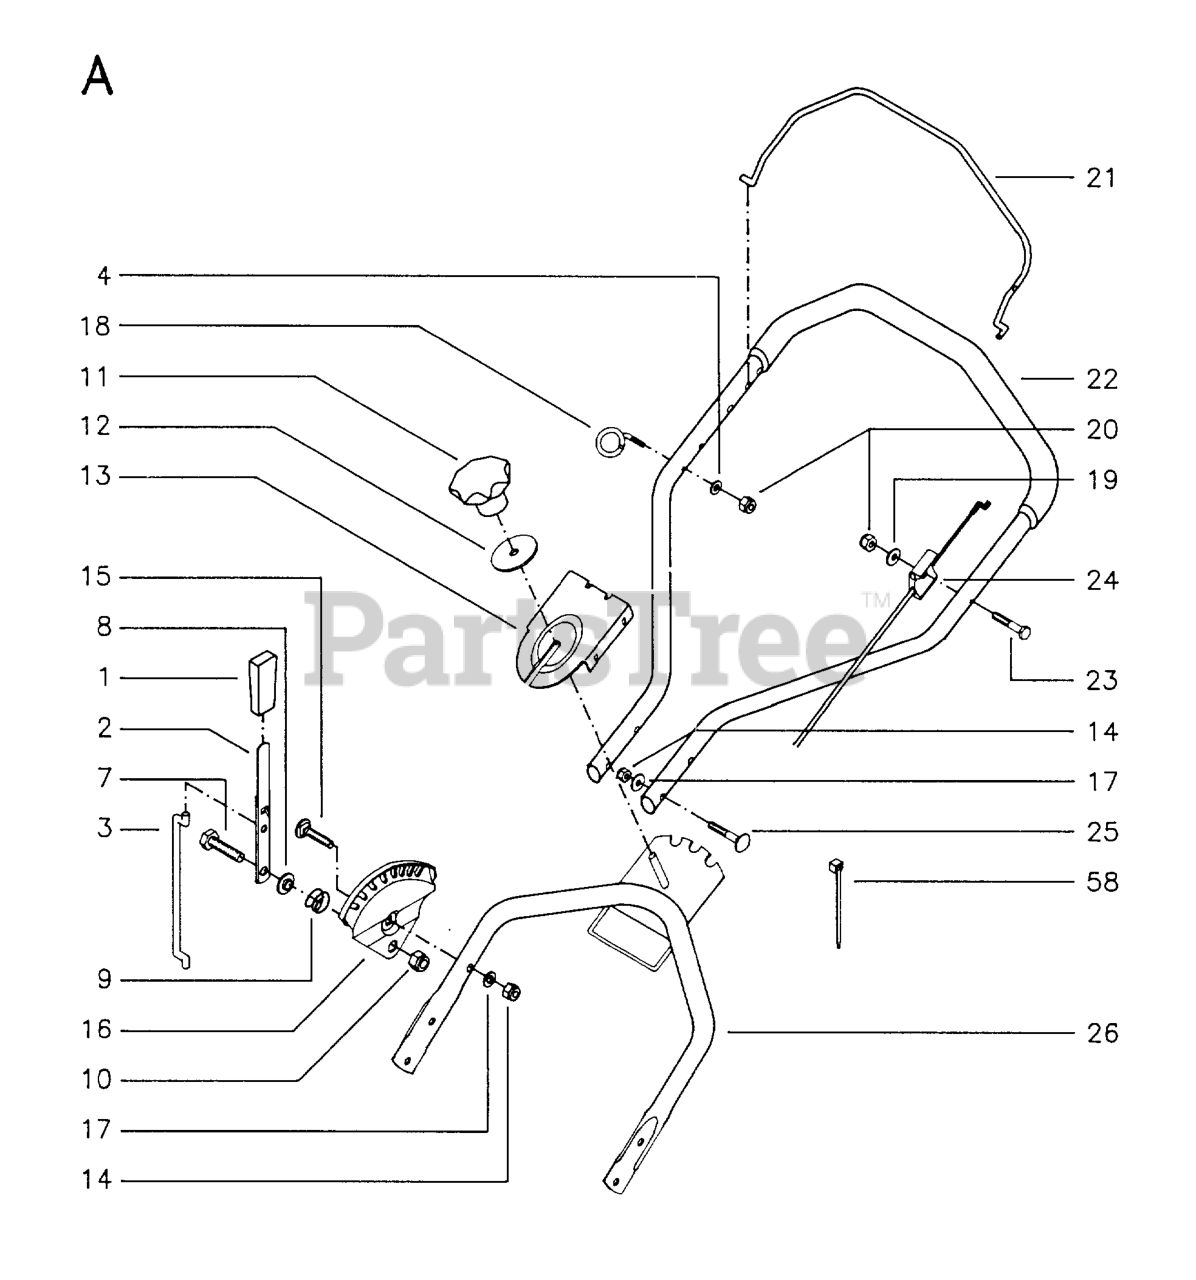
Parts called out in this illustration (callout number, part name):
2	CLUTCH ARM
9	PRESSURE SPRING
14	LOCKNUT M8
17	WASHER - 15X7.3X1.6
18	CABLE GUIDE
20	LOCKNUT M6
23	BOLT FLANGE
